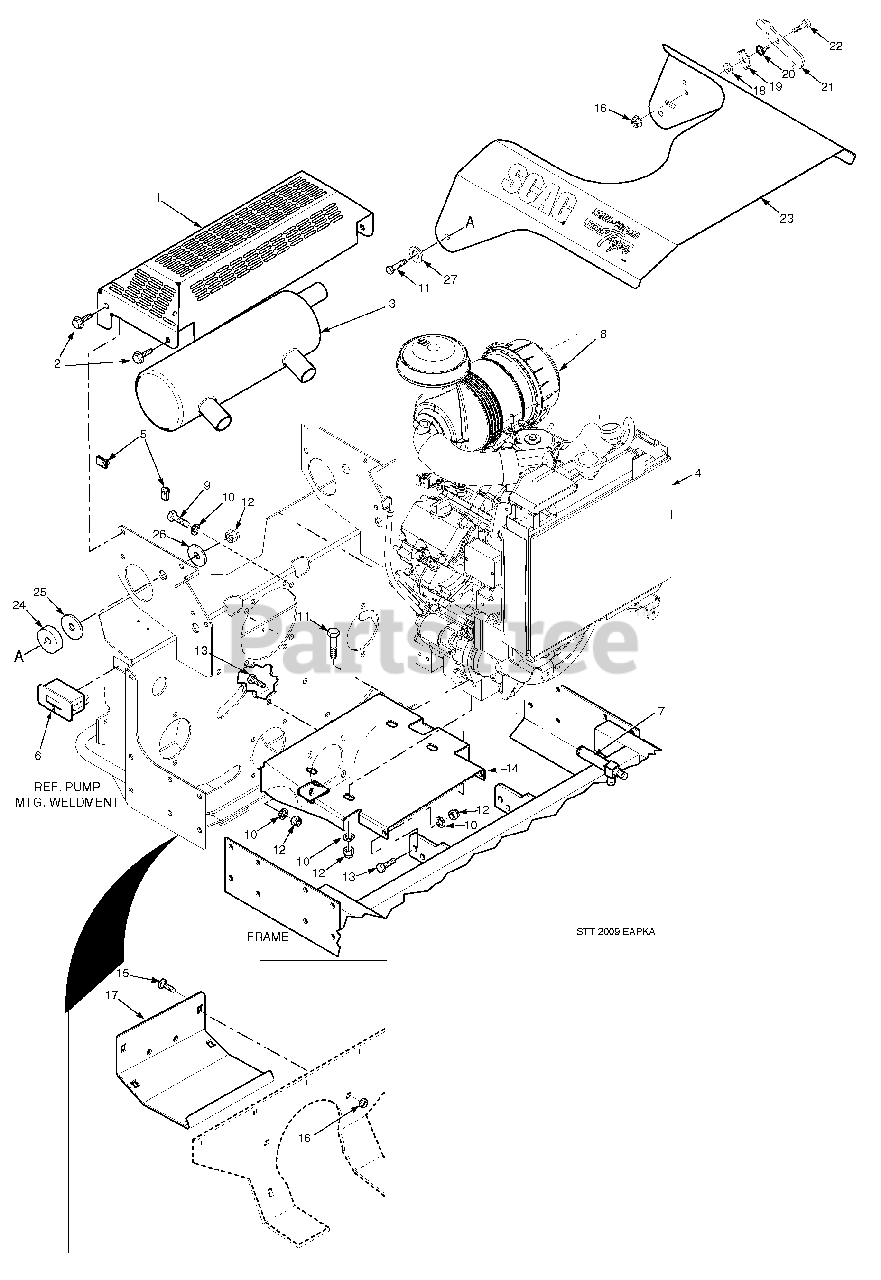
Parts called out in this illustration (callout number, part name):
1	Muffler Guard
2	Screw, Hex Serrated Flange 1/4-20 x 3/4"
3	Muffler
4	Screen Weldment, Radiator
5	U-Nut, 1/4-20
6	Hour Meter
7	Oil Drain, 2.6"
8	Engine, Kawasaki 27KA
9	Bolt, M10-1.50 x 25mm Grade 8.8
10	Lockwasher, 3/8" Spring
11	Bolt, Hex Head 3/8-16 x 1-3/4"
12	Nut, Hex Elastic Stop 3/8-16
13	Bolt, Hex Head 3/8-16 x 1-1/4"
14	Plate, Engine Mounting
15	Bolt, Carriage 5/16-18 x 3/4"
16	Nut, Hex Serrated Flange 5/16-18
17	Rear Cover
18	Flatwasher, 3/8 - .406 x .812 x .065
19	Lock, Hood Latch
20	Spring, Hood Latch
21	Latch, Hood
22	Bolt, Shoulder 5/16-18 x 1/2"
23	Hood Assembly w/Decals
24	Spacer, Hood
25	Disc, Anti-Friction
26	Flatwasher, 3/8 - .406 x 1.50 x 7 Gauge
27	Flatwasher, 3/8 - .391 x .938 x .105
